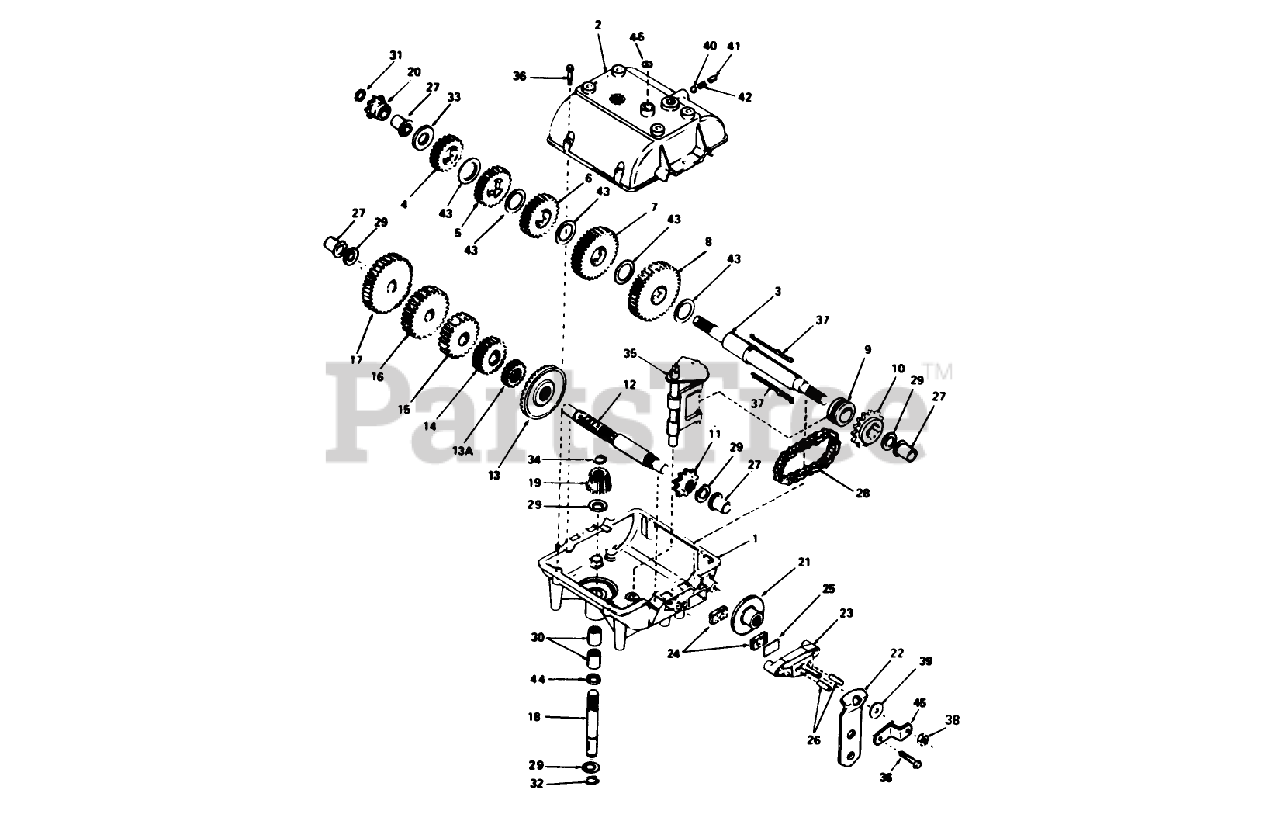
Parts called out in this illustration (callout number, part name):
1	Case-Transmission
2	Cover-Transmission
3	Shaft-Output Brake
4	Gear-Spur 20 teeth
5	Gear-Spur (22 teeth)
6	Gear-Spur, 25 Teeth
7	Gear-Spur, 30 Teeth
8	Gear-Spur, 35 Teeth
9	Collar-Shift
10	Sprocket-18 Teeth
11	Sprocket-9 Teeth
12	Countershaft
13	Gear-Bevel (42Teeth)
13A	Gear-Spur 15 Teeth
14	Gear-Spur, 20 Teeth
15	Gear-Spur, 25 Teeth
16	Gear-Spur (28 teeth)
17	Gear-Spur (30 teeth)
18	Shaft-Input
19	Bevel Pinion-Input
20	Sprocket (8 teeth)
22	Lever-Brake
23	Nozzle-Carburetor
24	Brake Pad
25	Brake Pad Plate
26	Dowel Pin
27	Bushing-Flange
28	Chain-Roller #41
29	Washer
30	Bearing-Needle
31	Piston Asm (.020 O S)
32	Ring-Snap
33	Washer
34	Ring-Retainer
35	Rod and Fork ASM
36	Ring Set (.020 O S)
38	Locknut
39	Washer
40	Ball-Steel
41	Screw-Set
42	Spring
43	Washer
44	O Ring
45	Bracket
46	Cut Seal-Square
